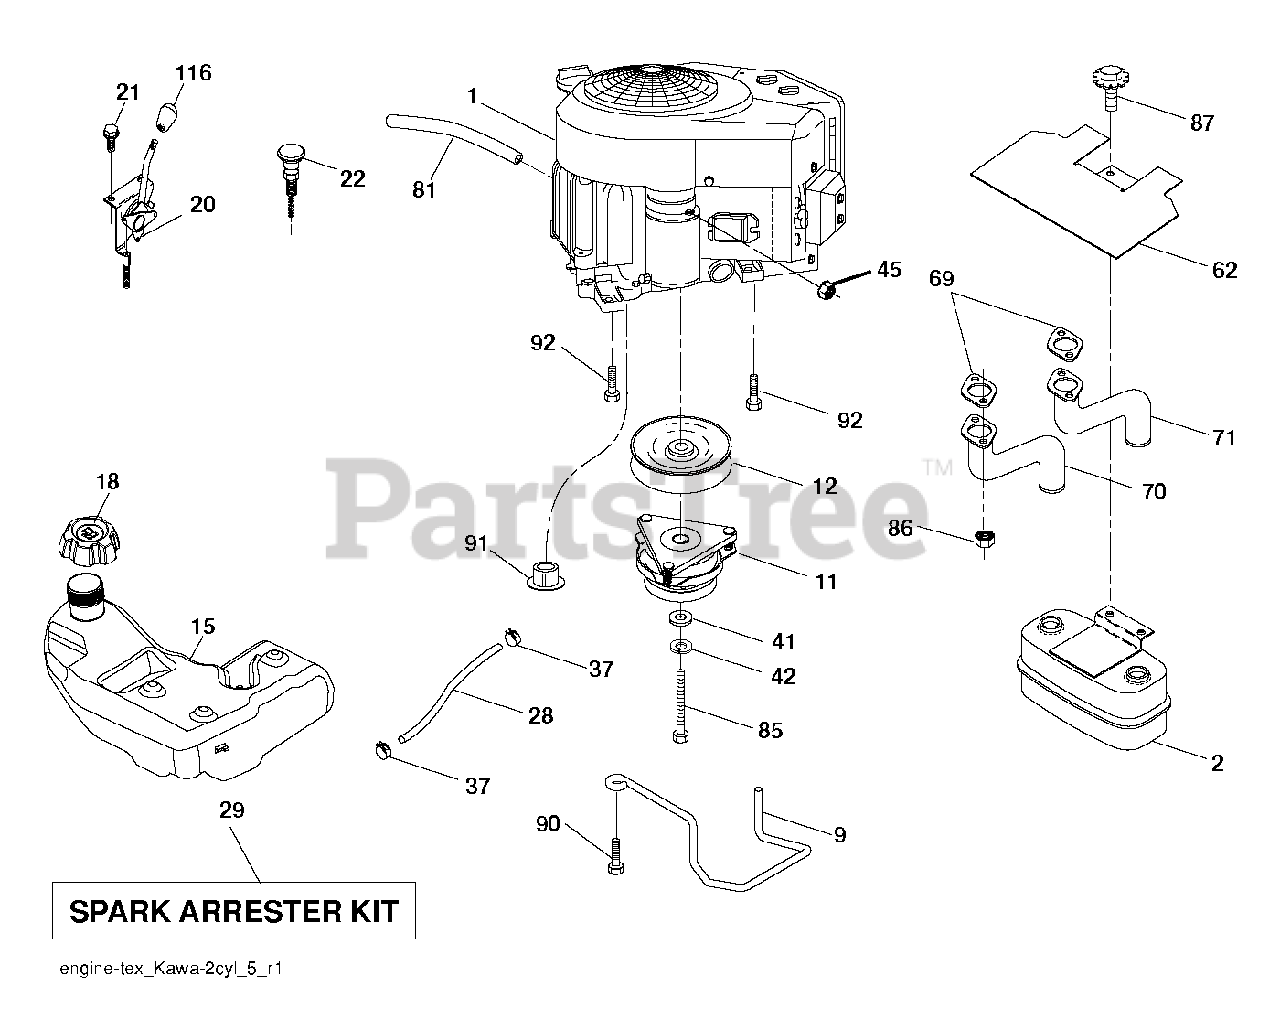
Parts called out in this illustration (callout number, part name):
2	MUFFLER.ASM.TWN.EXTNDED.DFLCTR
9	KEEPER BELT ENGINE
11	CLUTCH.ELECTRIC.LT.48"*
12	PULLEY.ENGINE.TUFFTORQ
15	TANK.ASSY.3.GAL.EPA
18	CAP.ASM.FL.RITCH.3"E10.SYM.498
20	CONTROL.THROTTLE.PRO.
21	SCREW.#10 X 0.750.BOS
22	CONTROL, CHOKE
28	LINE.FUEL.64"REAR.EMIS
29	KIT.SPARK ARRESTOR 794945 B&S
37	HOSE CLAMP
42	LOCKWASHER
45	NUT
62	SHIELD.HEAT.MUFFLER
70	TUBE.EXHAUST.LH.FR961/FR730
71	TUBE.EXHAUST.RH.FR961/FR730
81	TUBE, DRAIN OIL ASM.
85	BOLT HEX 7/16-20X4-1/4"
86	NUT.HEX.FLANGE.TOPLOCK
87	Bolt, 5/16-18 X 1-3/4
90	SCREW 3/8-16X1
91	BUSHING.1.375OD
92	SCREW 3/8-16X1
116	KNOB - SHIFT
